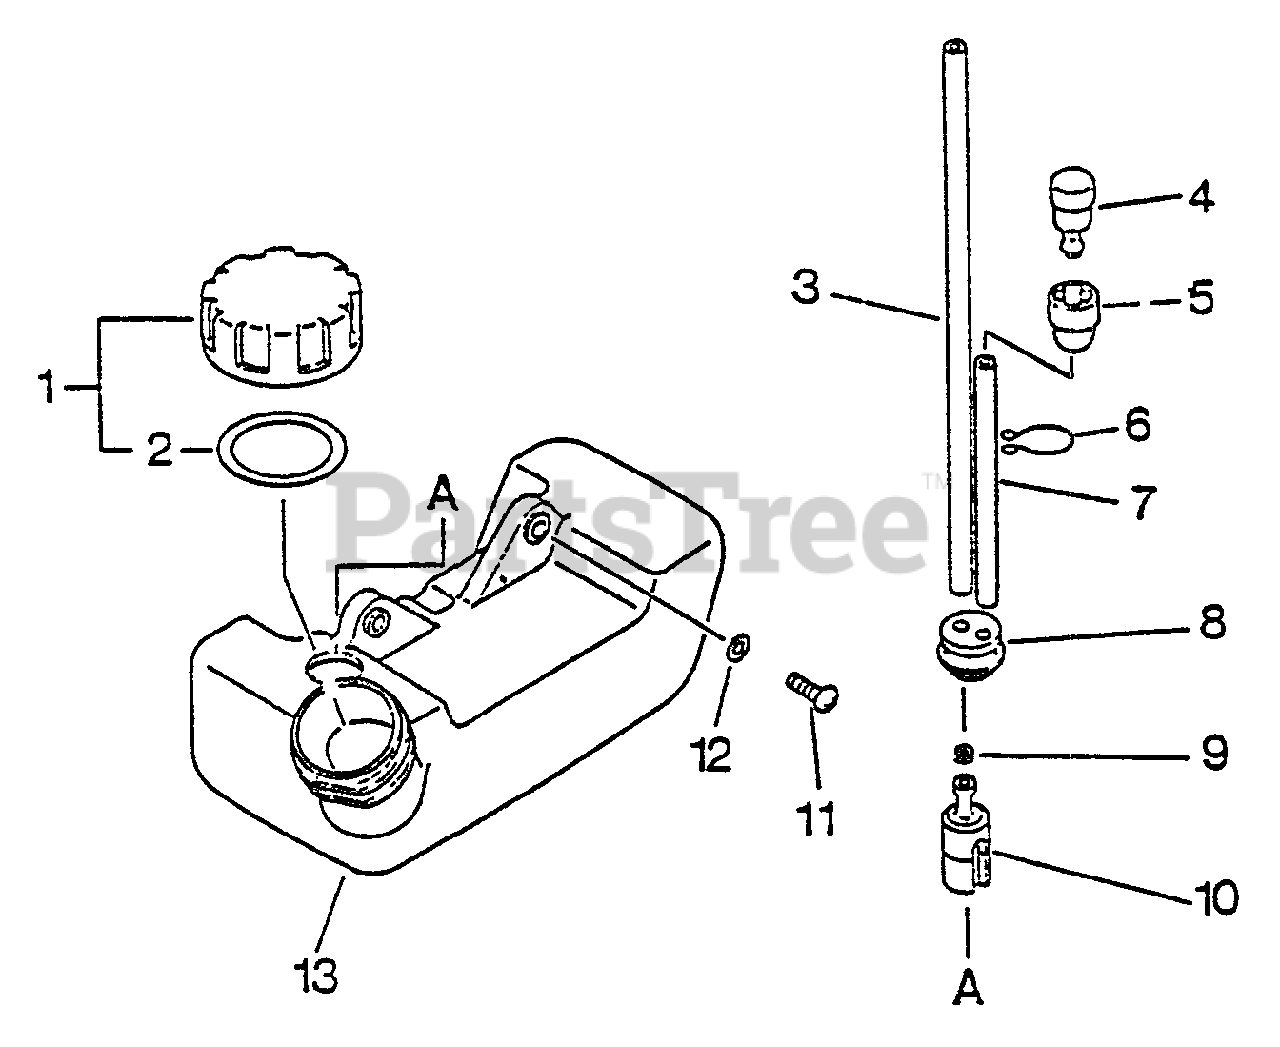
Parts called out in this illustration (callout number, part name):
1	CAP ASSY
2	GASKET, CAP
3	PIPE - 3X5X180 -- BLACK
4	VENT, FUEL TANK
5	COVER, VENT
7	PIPE - 3X6X70 -- CLEAR
8	GROMMET
9	CLIP - 6
10	FILTER, FUEL
11	SCREW - 5X16
12	WASHER - 5
13	TANK, FUEL
